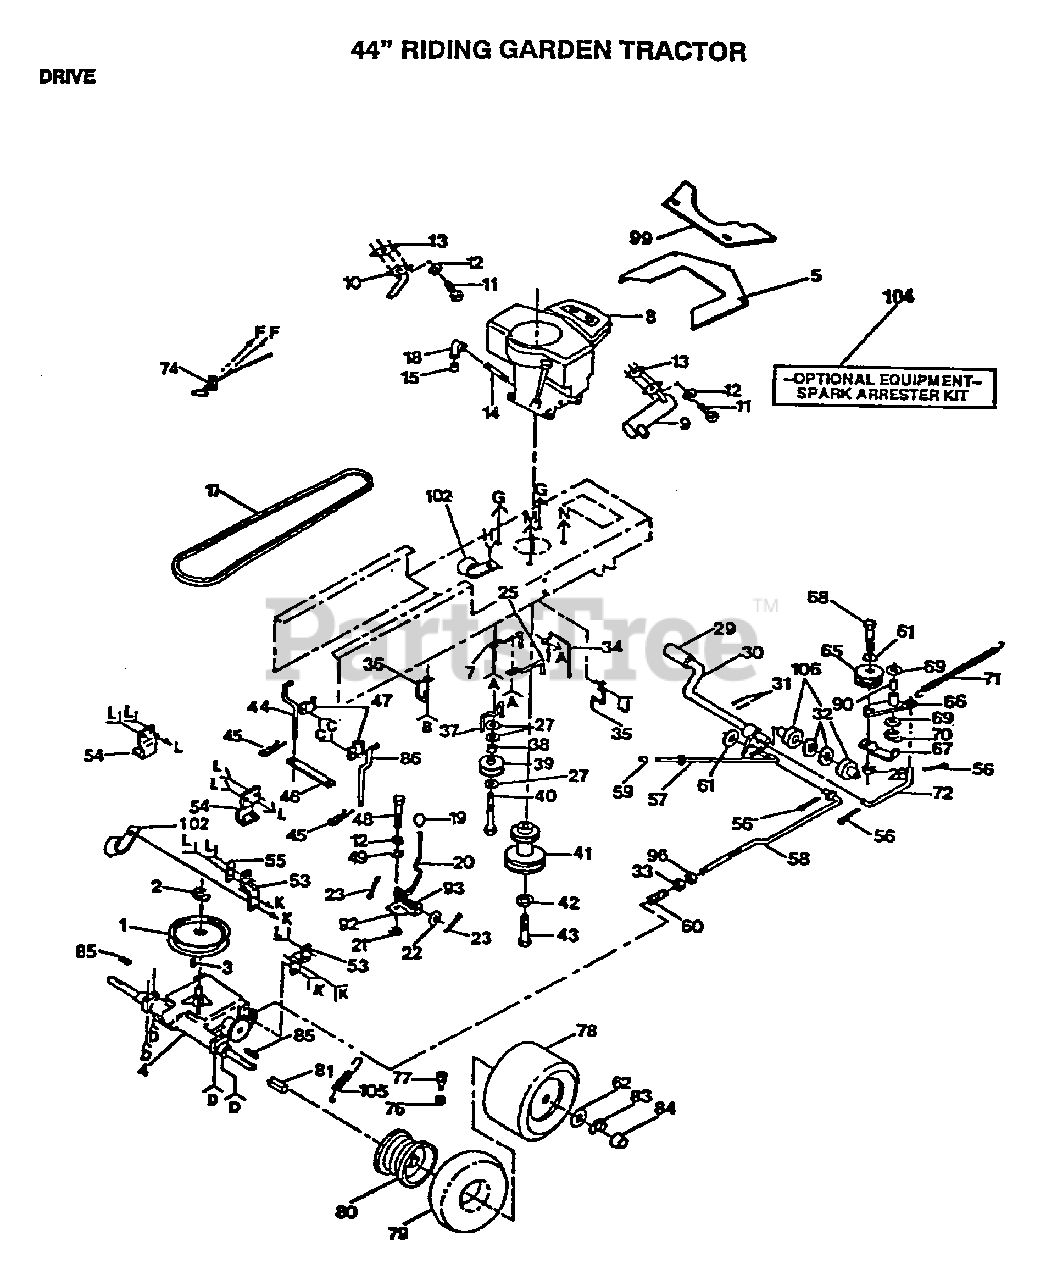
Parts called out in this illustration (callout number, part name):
1	PULLEY TRANSAXLE
2	RING
4	TRANSAXLE PEERLESS
5	SHIELD HEAT FRT
6	WASHER
7	KEEPER BELT ENGLH
10	EXHAUST TUBE T
12	LOCKWASHER
14	PIPE NIPPLE
17	V BELT
18	STREET ELBOW LT
19	KNOB T (1/2-HOLE)
20	ROD SHIFTER T
21	WASH-SHFT PLT LT
22	WASHER
23	PIN COTTER 1/8
24	SCREW
25	"KEEPER,BLT ENG LT"
26	BOLT
27	WASHER
29	PEDAL COVER T
32	WASHER LT
33	NUT
34	BELT GUIDE
35	BELT GUIDE
37	BELT KEEPER LT
38	SPACER T
39	IDLER.FLAT.GTV
40	BOLT
42	LOCKWASHER
43	BOLT
45	SPRING.RETAINER
46	STRAP LOCATOR
47	CLAMP LT
49	WASHER LT
50	BOLT
52	BOLT HEX
53	STRAP TORQUE
54	BRACKET LT
55	PLATE-STRAP LT
56	COTTER PIN
57	ROD BRAKE PARK
58	ROD BRAKE
59	PLUNGER CAP T
60	SPRING ROD LT
61	WASHER
62	WASHER
66	ARM IDLER
67	RETAIN BELT
69	WASHER LT
70	KLIP RING
71	"SPRING, RETURN LT"
72	"LINK, CLUTCH T"
75	SCREW LT
76	VALVE CAP
77	VALVE STEM LT
79	TUBE.18X9.5-8
81	SPACER HYT
83	E RING HYT
84	HUB CAP
85	SQ KEY STD
87	SCREW LT
90	"LY, BEARING"
92	PLATE SHIFT LT
93	SPRING LT
94	LOCKWASHER
95	NUT
96	NUT
98	WASHER
99	REAR BAFFLE T
101	SCREW
102	CLIP T
106	NYLON BEARING
